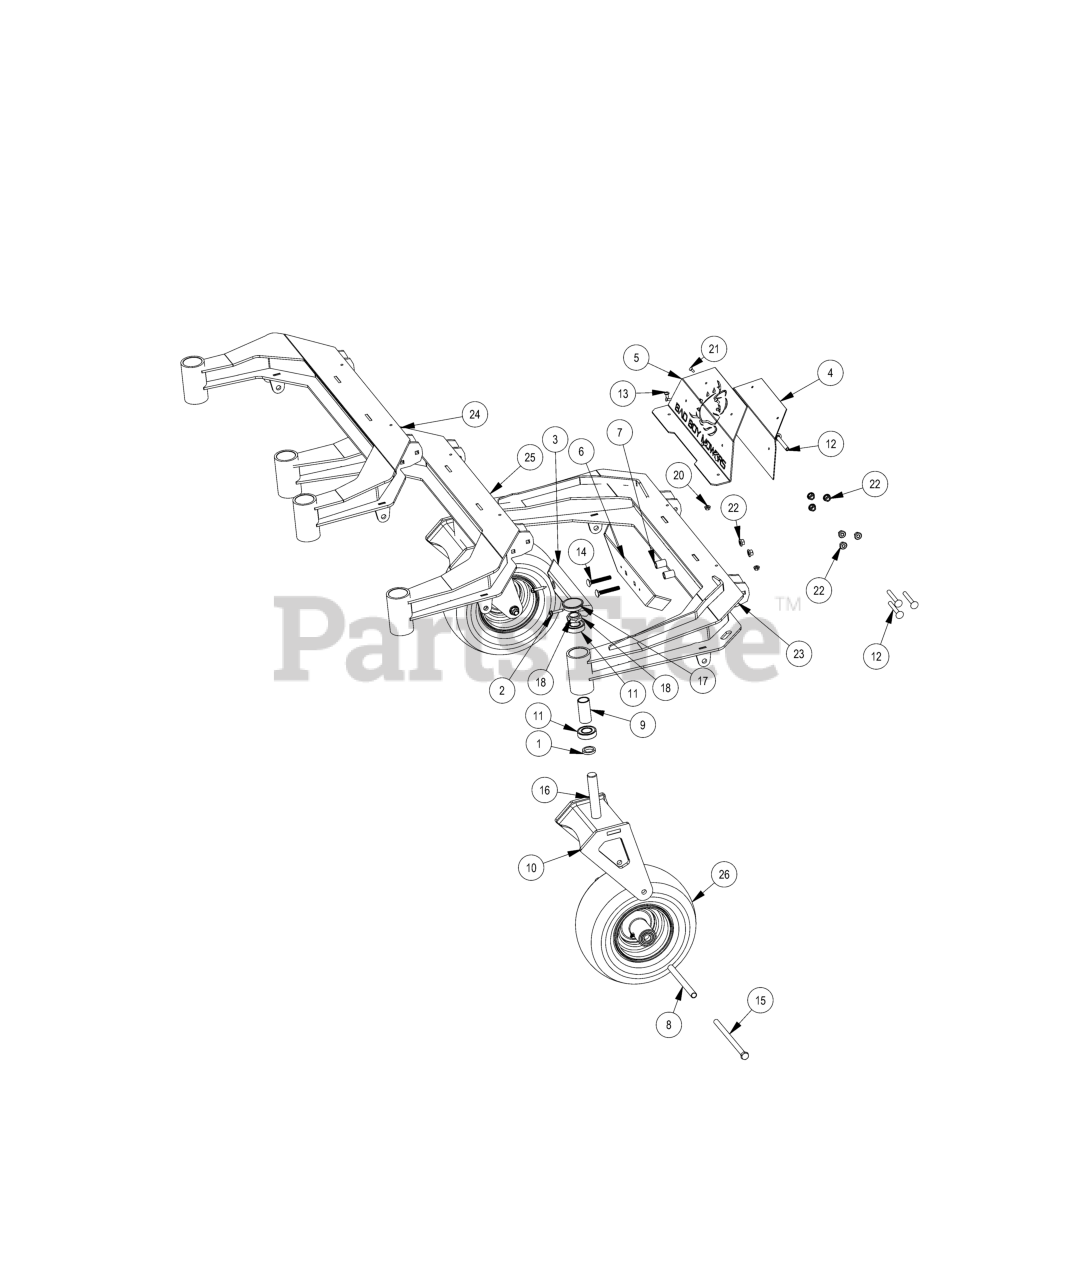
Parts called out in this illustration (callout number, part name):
1	1.02 ID X 1.38 OD X .250 THK SPACER ZINC
2	1/4-14 X 1-1/2 HEX WASHER UNSLOT TEK/3 ZINC
3	Bumper EZT
4	Exhaust Backer Plate 2019 Stand On
5	Exhaust Shield Plate 2019 Stand On
6	2019 Stand On Front Bumper Plate
8	Front Wheel Spanner
9	2016 Front Bearing Spacer
10	2019 Stand-on Front Fork Weldment
11	1641 BEARING W/2 CONTACT RUBBER SEALS
12	3/8-16 X 3 CARRIAGE BOLT ZINC GR5
13	1/4"-20 x 3/4 Black Oxide 18-8 Stainless Pan Head
14	3/8" x 2 1/2" Carriage Bolt
15	1/2-13 X 8-1/2 HEX CAP SCREW (GR.5) ZINC
16	1"-14 X 5-1/2 HEX CAP SCREW (GR.8) ZINC YELLOW
17	2017 Bearing Cover
18	1"-14 NYLON INSERT JAM LOCKNUT ZINC
19	1/2-13 NYLON INSERT FLANGE LOCKNUT ZINC
20	1/4-20 NYL INSERT FLANGE LOCKNUT ZINC
21	3/16" Diameter Black Rivet, for 0.1260"-0.25" Material Thick
22	3/8-16 NYLON INSERT FLANGE LOCKNUT (GR.F) ZINC
23	2023 Stand-On 61 Front End Weldment
24	2023 Stand-On 48 Front End Weldment
25	2023 Stand-On 54 Front End Weldment
26	13x6.50-6 Black No Flat Assembly
